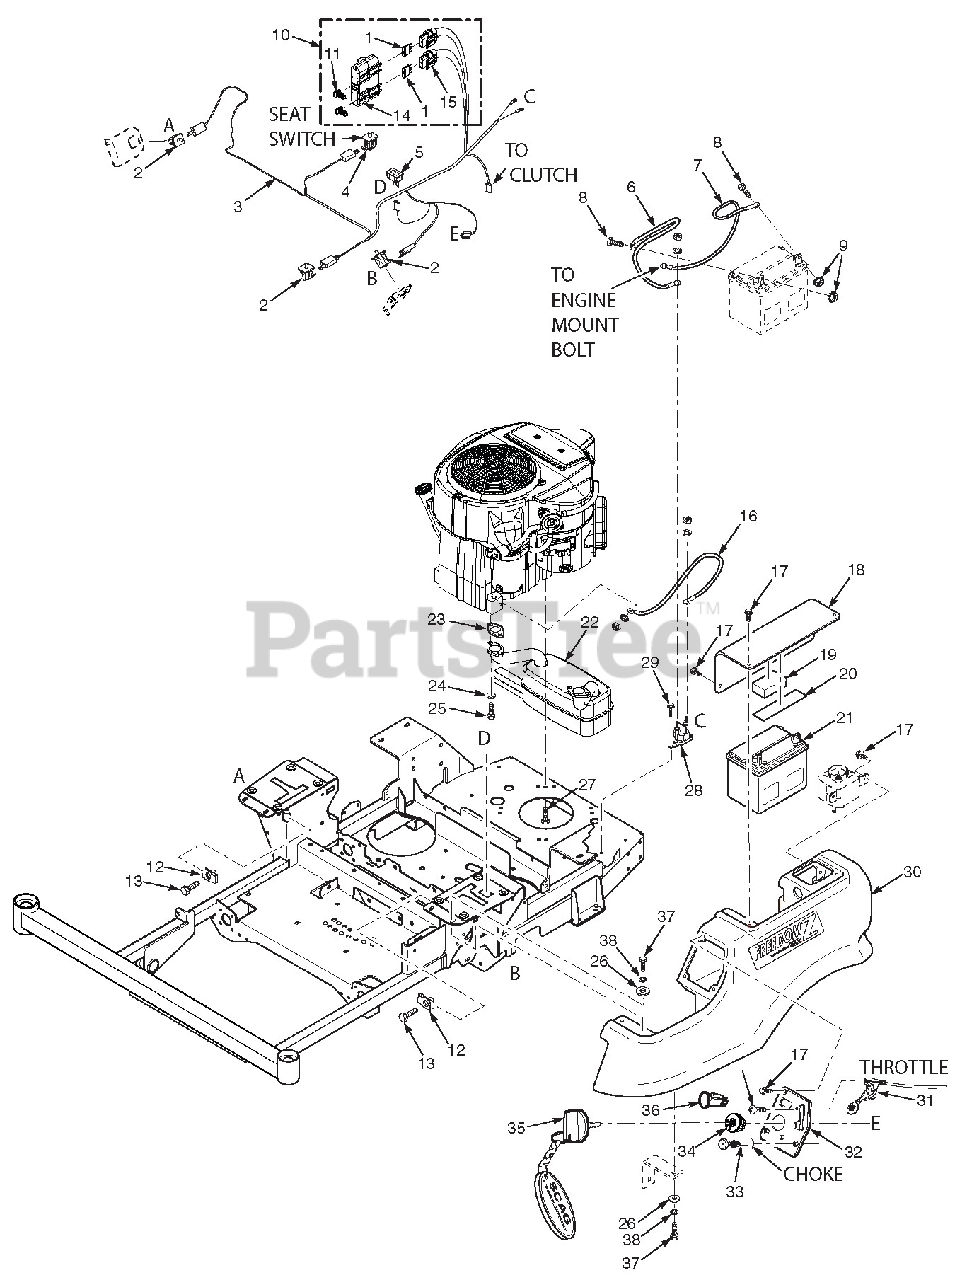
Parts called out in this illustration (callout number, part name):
1	Fuse, 20 amp
2	Switch
3	Wire Harness, Main
4	Switch, Seat
5	Hourmeter
6	Battery Cable, Red 25"
7	Battery Cable, Black 27"
8	Bolt, Hex Head 1/4-20 x 1/2"
9	Nut, 1/4-20
10	Double Fuse Assy.
11	Clip, Wire
12	U-Nut, 3/8-16
13	Bolt, Hex Head 3/8-16 x 1-1/4" Special Lock
14	Cover, Sealed Double
15	Fuse Holder
16	Battery Cable, Red 9"
17	Bolt, Hex Head 1/4-20 x 1/2" Serr. Flange
18	Battery Cover
19	Pad, Battery Hold Down
20	Rubber Pad
21	Battery
22	Muffler, Kawasaki FR600V
22	Muffler, Kawasaki FR651V
22	Muffler, Kohler KT
23	Exhaust Gasket
24	Lockwasher
25	Bolt
26	Flatwasher, 5/16-.375 x .875 x .083
27	Bolt, Hex Head 3/8-16 x 1-1/4" (Kawasaki)
27	Lockwasher, 3/8" Spring (Kawasaki)
28	Solenoid
29	Bolt, Self Tapping 1/2-20 x 3/4" Shakeproof
30	Tank, LH
31	Throttle Cable - Kawasaki
31	Throttle Cable - Kohler
32	Instrument Panel w/Decal
33	Choke Cable - Kawasaki
33	Choke Cable - Kohler
34	Ignition Switch
35	Key, Ignition
35	Key w/Shroud
35	Key Assembly w/Fob
36	PTO Switch
37	Bolt, Hex Head 5/16-18 x 3/4"
38	Lockwasher, 5/16" Spring
